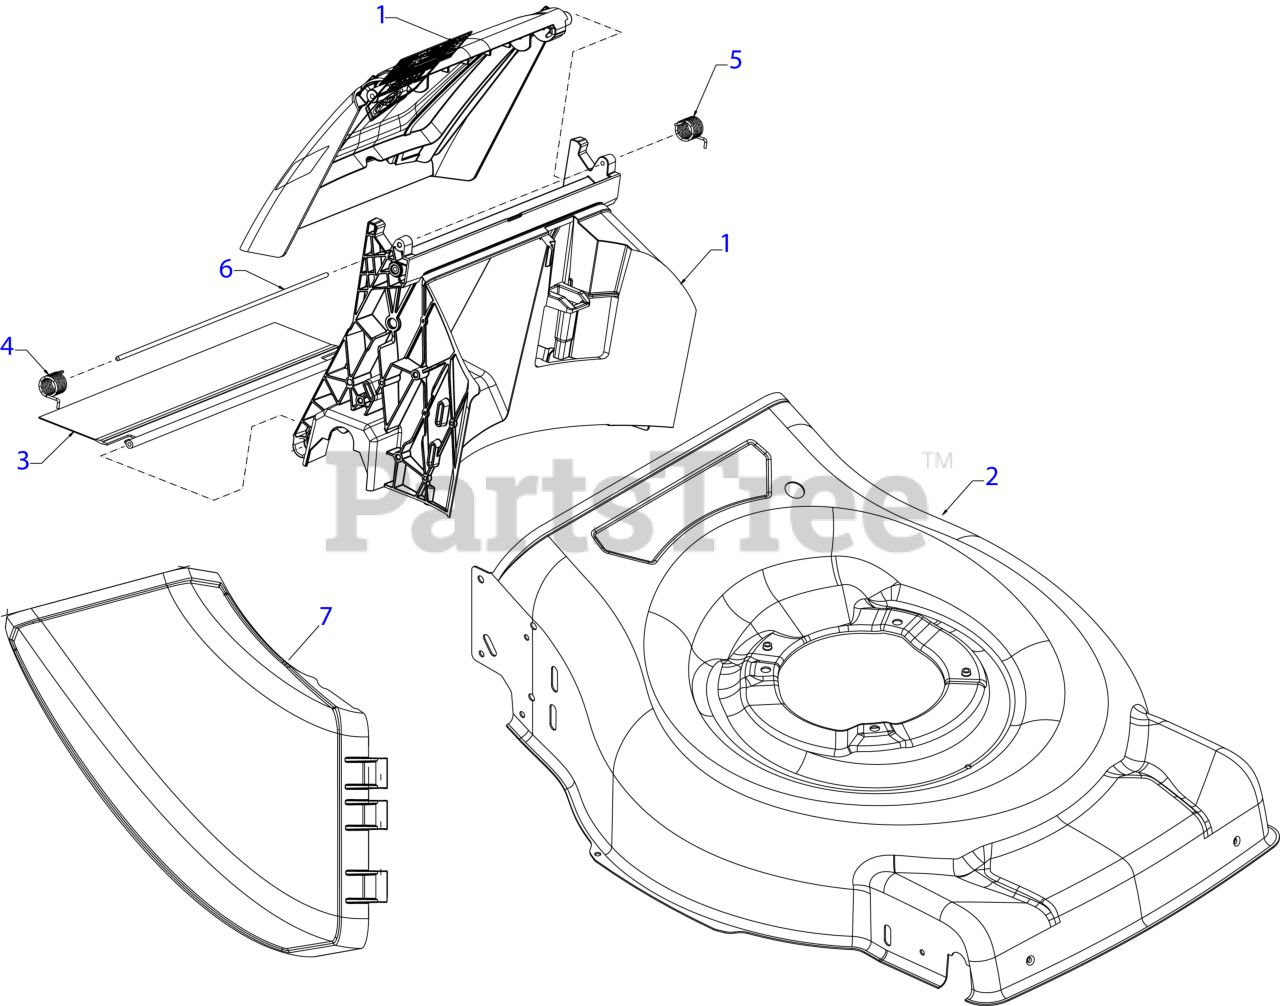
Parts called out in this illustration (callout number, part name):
1	BAFFLE ASSEMBLY
2	23" DECK
3	TRAILSHIELD (4.54 x 18)
4	TORSION SPRING (RH)
5	TORSION SPRING (LH)
7	REAR DISCHARGE CHUTE
